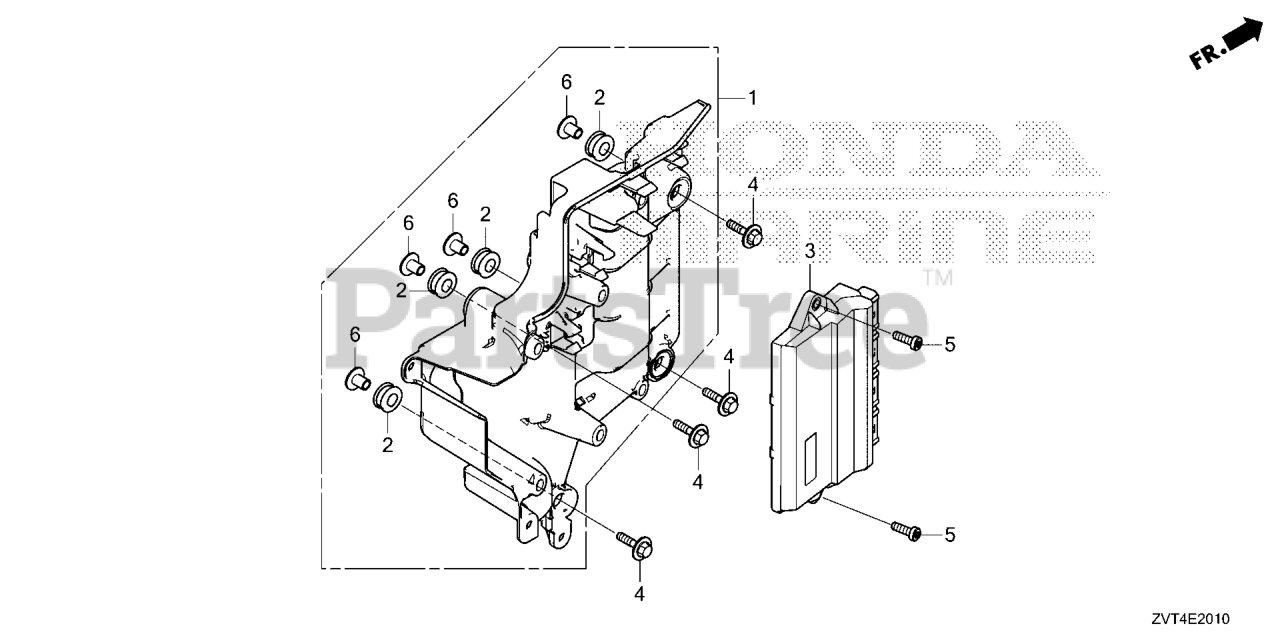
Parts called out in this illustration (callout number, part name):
1	CASE, ELEC PARTS
2	GROMMET, ELECTRONIC PARTS CASE
3	CONTROL UNIT, EL
4	BOLT-WASHER (6X27)
5	BOLT, TORX (M6X20)
6	COLLAR (12X6.5)
